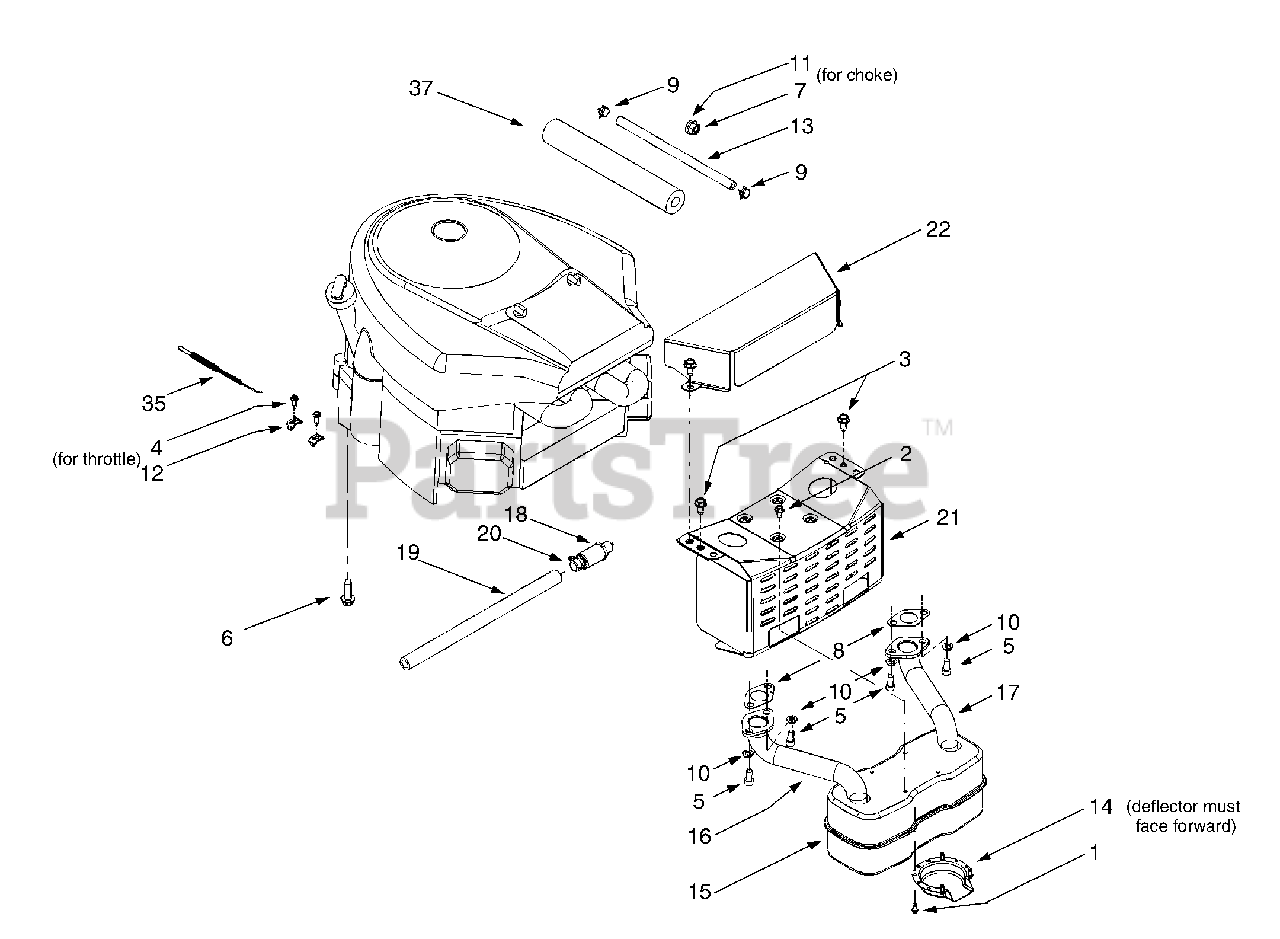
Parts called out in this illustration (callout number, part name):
1	Self-tapping Screw, #8-32 x .375
2	Self-tapping Screw, 1/4-20 x .5
3	Self-tapping Screw, 5/16-18 x .625
4	Screw, #10-32 x .625
5	Socket Cap Screw, 5/16-18 x .625
6	Self-tapping Screw, 3/8-16 x 1.25
7	Hex Nut, 3/8-16
8	Exhaust Gasket
9	Hose Clamp
10	Lock Washer, 5/16
11	Flat Washer, .406 x .875 x .059
12	Casing Clamp
13	Fuel Line Hose
14	Muffler Deflector
15	Muffler, Twin Inlet
16	RH Exhaust Pipe
17	LH Exhaust Pipe
18	Oil Drain Valve
19	Oil Drain Hose
20	Oil Drain Cap
22	Engine Heat Shield
35	Throttle Cable
37	Foam (fits over fuel line)
